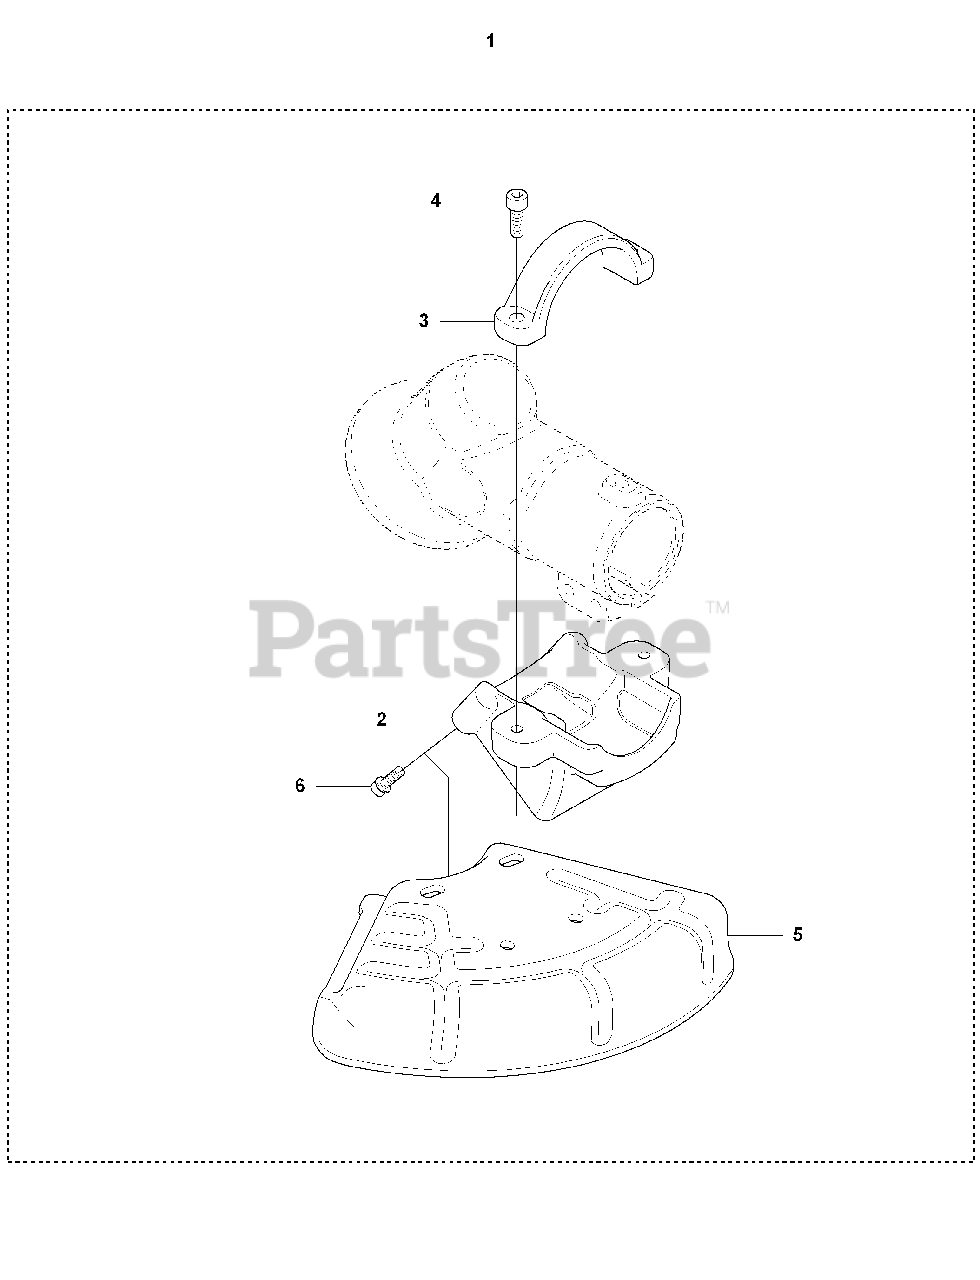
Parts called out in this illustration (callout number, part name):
2	BLADE GUARD SAW
5	BLADE GUARD SAW
6	SCREW IHSCFM
